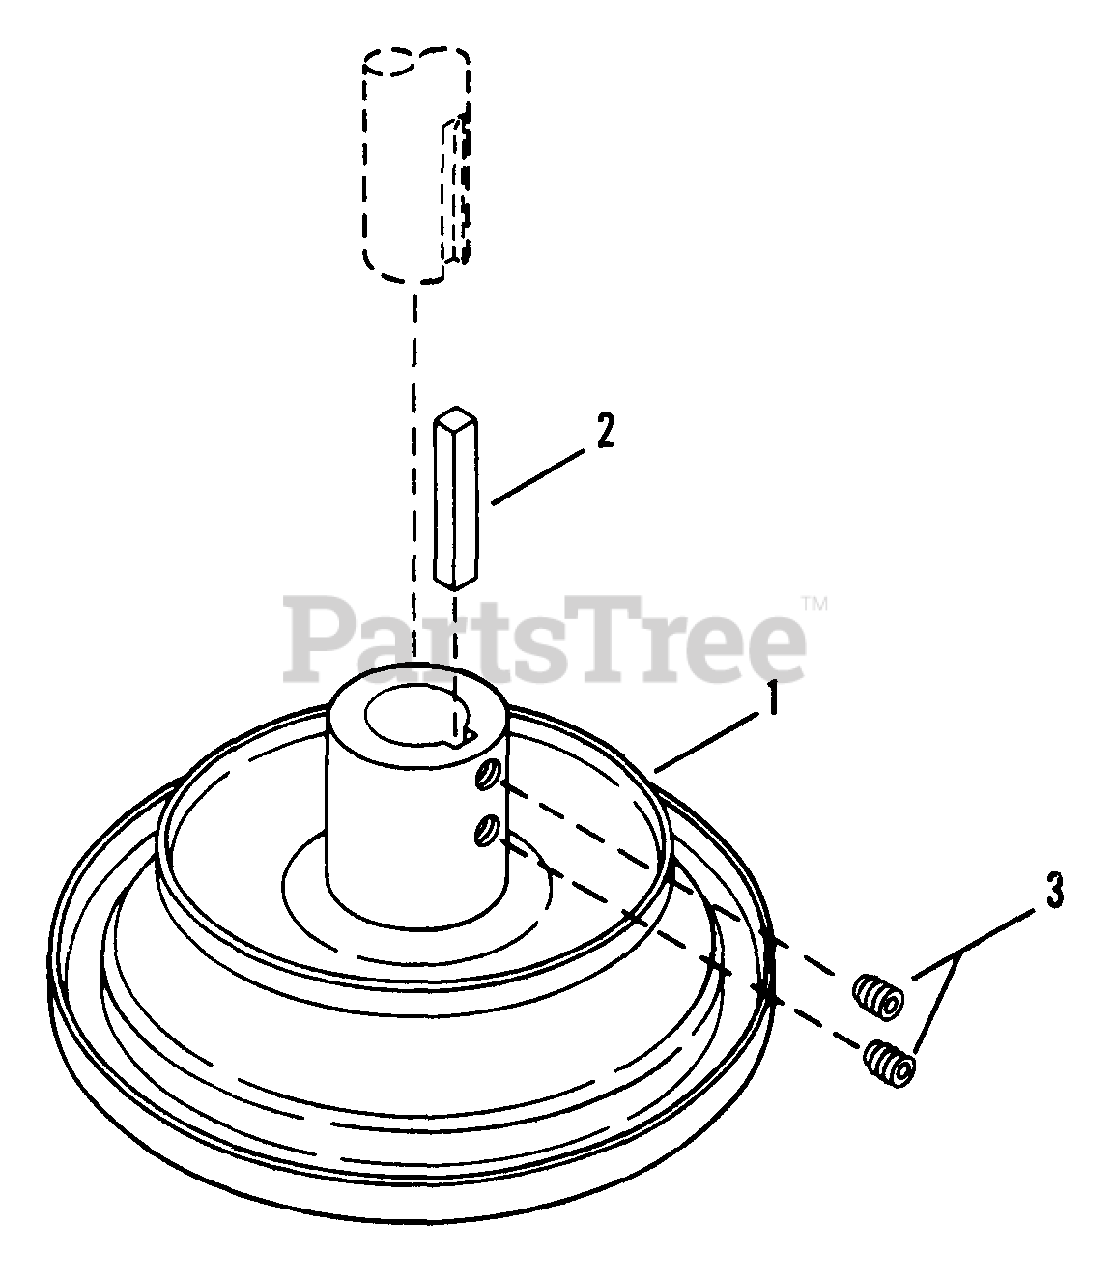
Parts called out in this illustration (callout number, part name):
1	ASSEMBLY, Drive Disc (25", 26", & 28" Models)
2	KEY, 1/4 x 1/4 x 2" Square
3	SCREW, 3/8-16 x 3/8" Socket Set
